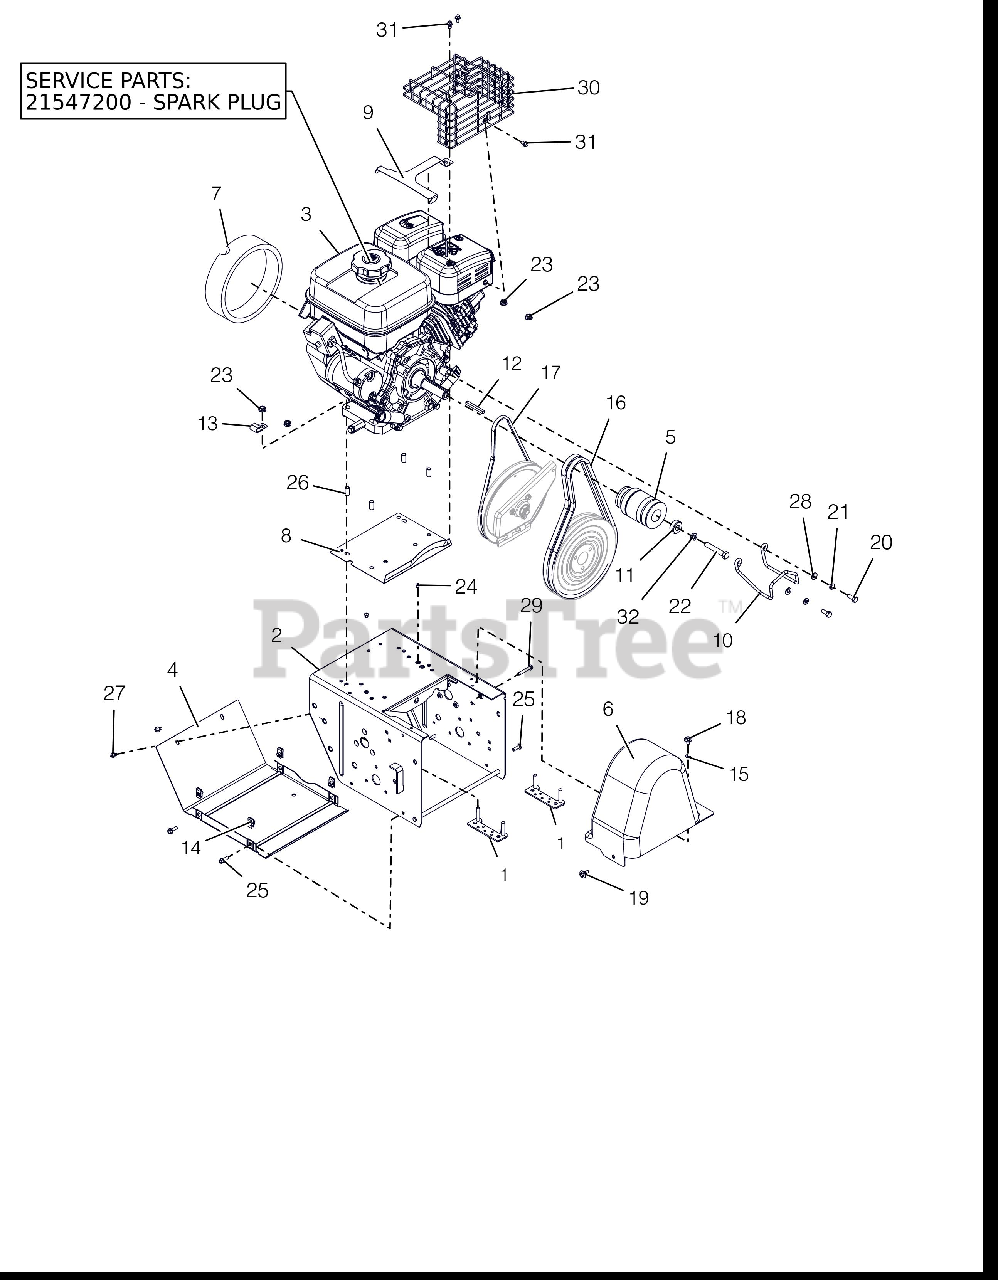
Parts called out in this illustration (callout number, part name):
1	STRAP, ENGINE BOLT-LARGE BRIGG
2	FRAME, MAIN - PRO (WELDMENT)
3	ENGINE,SUBARU EX27 AS 120V
3	PLUG, SPARK SUBARU
4	COVER, BOTTOM
5	SHEAVE, SUBARU EX27
6	COVER, BELT-TALL PRO
7	FOAM COVER, RECOIL-SUBARU
8	BAFFLE, WATER - LARGE BLOCK
9	GUARD, SNOW-SUBARU
10	FINGER, BELT
11	BSHG-SPACER .47X1.25X.50
12	KEY .25X.25X2.25
13	J-CLAMP
14	NUT-RTNR .25-20X.56
15	NUT-PUSH .25X.50 O.D.
16	V-BELT, HA-RAW EDGE (SET)
17	V-BELT, 3L-RAW EDGE
18	SCR-TAP .25-20X.50 LGHWH TR YZ
19	SCR-TAP .25-20X.5 CAPTIVE
20	BLT-HEX .31-24X.75 YWZC GR5
21	WSHR-LK .312X.097 HVY YWZC
22	BLT-HEX .44-20X1.50 G5 YZ EP80
23	@NUT-LK-CTR-FLG .31-18 YZ GR F
24	RVT-POP .187 YZ
25	BLT-HEX .25-20X.75 HWH YZ GR5
26	BSHG-SLV .325X.400X.795
27	SCR-TAP .25-20X.50 HWH TR YWZ
28	@WSHR-FL-STL.344X.688X.065YWZC
29	@SCR-TAP .25-20X1.50 HWH TR YZ
30	MUFFLER GUARD, SUB EX270JO930
31	BLT-SERHFWH M6X1.0X12 8.8 CZ
32	@WSHR-LK .44X.109 REG YWZC
